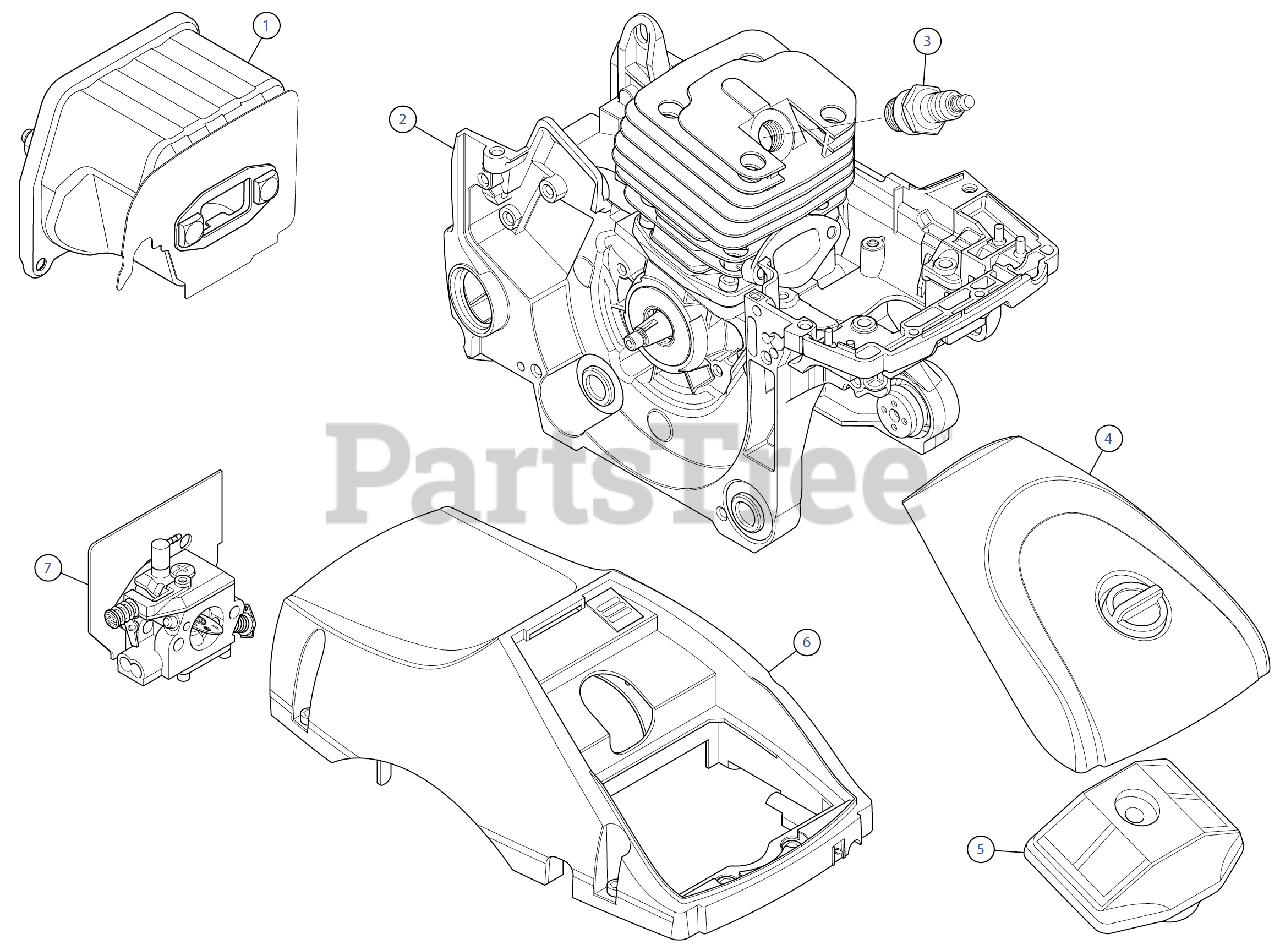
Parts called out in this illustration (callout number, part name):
1	MUFFLER ASSEMBLY
2	SHORT BLOCK 42CC YD4200.8-31000
3	SPARK PLUG:L8RTF YD4500-26200
4	AIR FILTER COVER ASSEMBLY
5	AIR FILTER W/SEAL
6	COVER
7	CARBURATOR
